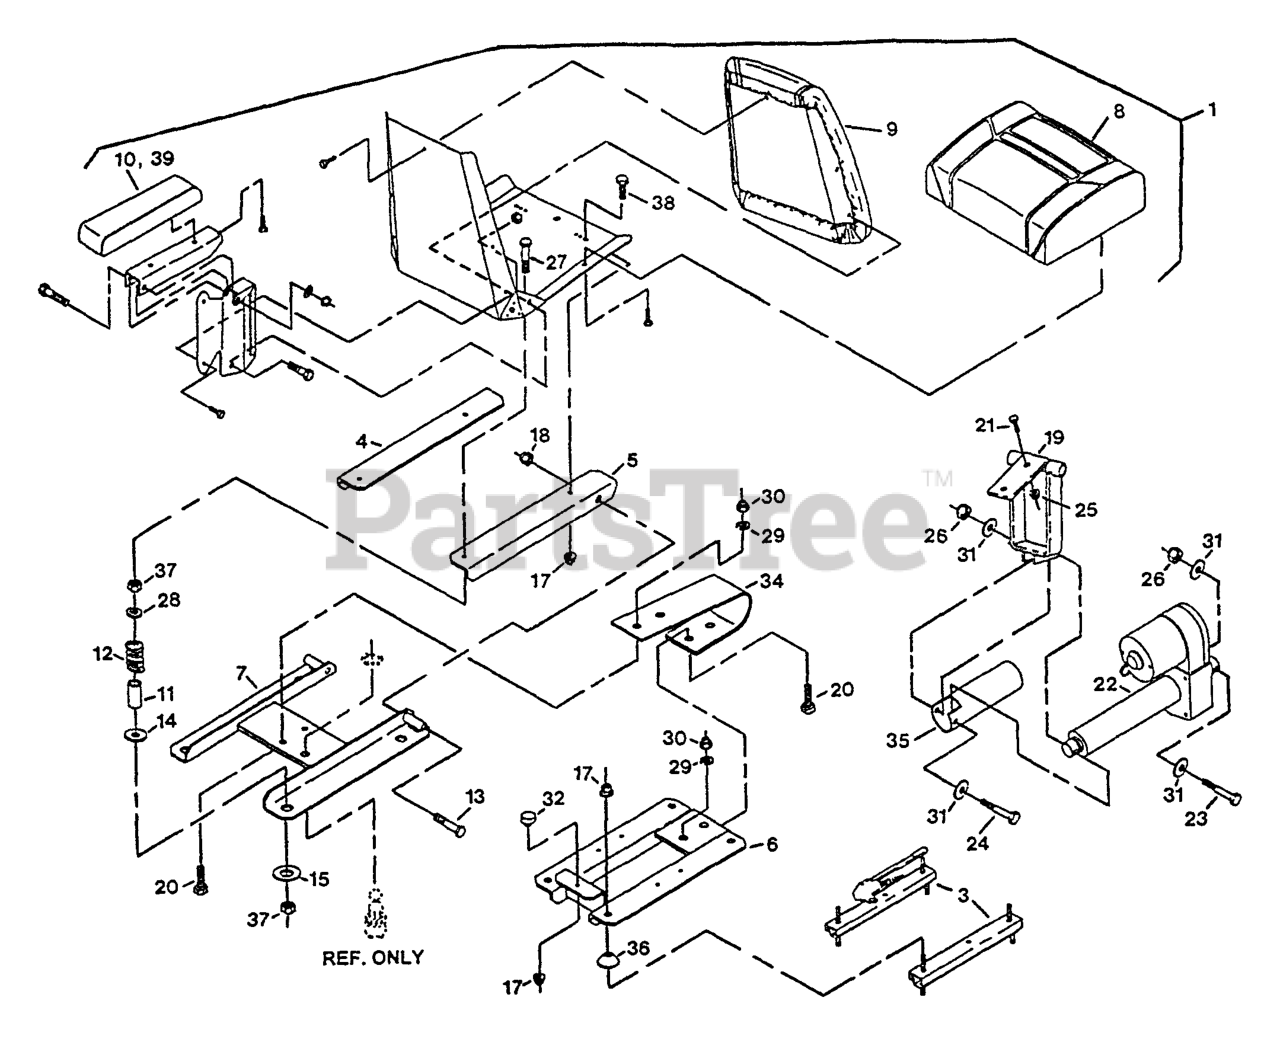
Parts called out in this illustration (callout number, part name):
4	RAIL,SEAT LH
5	RAIL,SEAT RH
6	WLD,RAIL BASE
11	BUSHING,SPRING GUIDE
12	SPRING-INDICATOR, REVERSE
16	SWITCH,PUSH BUTTON
27	BOLT,TAP HH
32	BUMPER-RUBBER
34	SPRING,RANGER SEAT
35	GUARD,ACTUATOR
36	SPACER-TRACK
